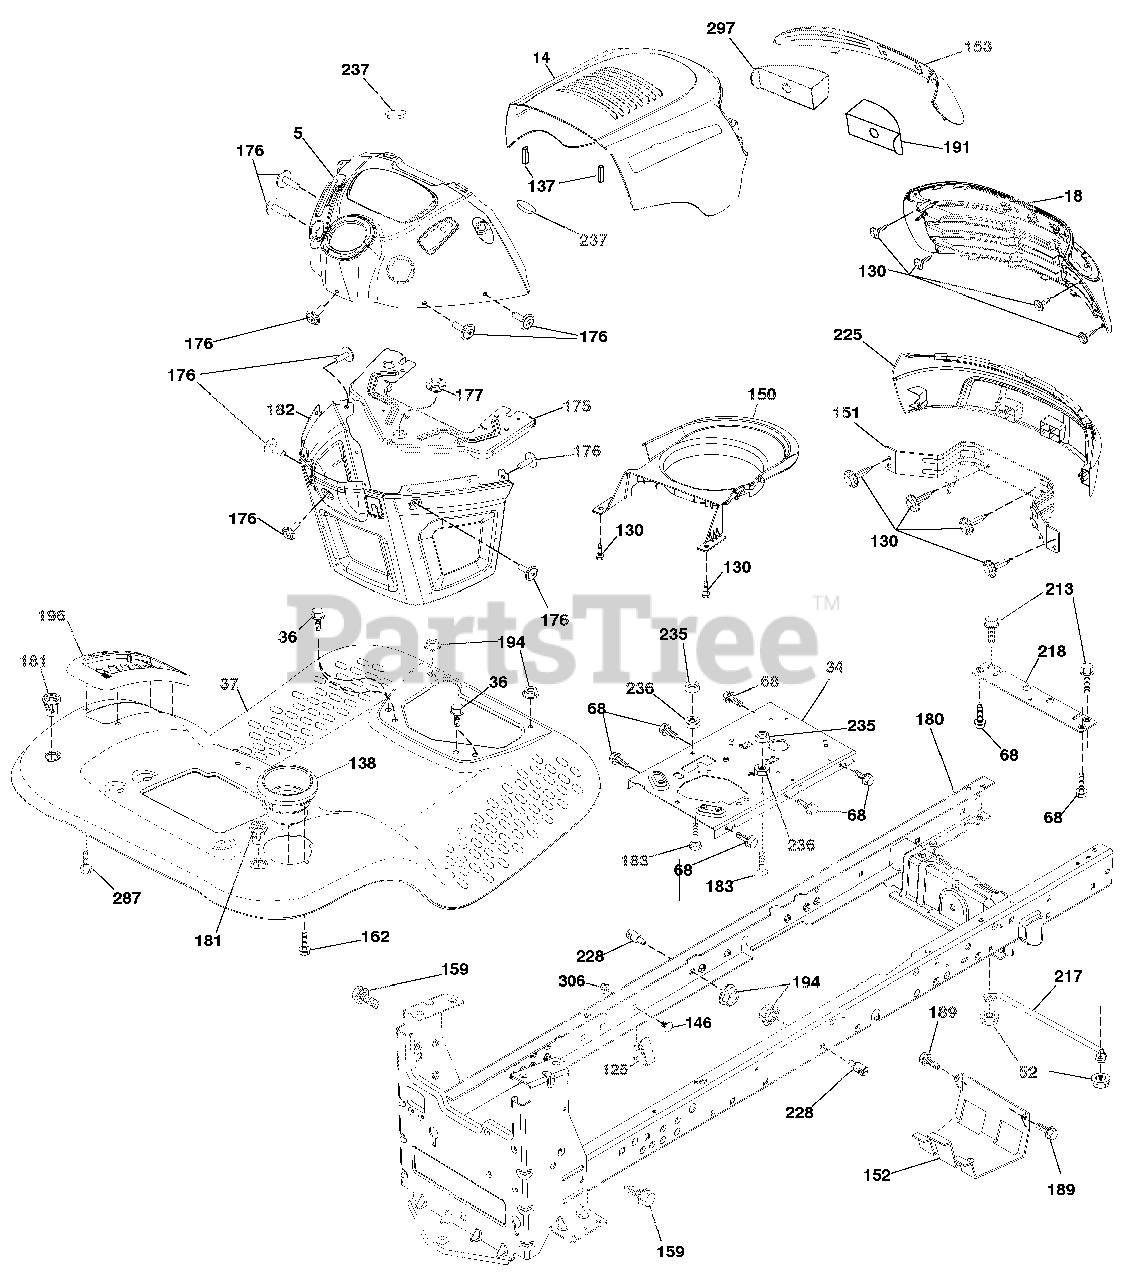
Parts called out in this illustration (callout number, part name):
5	DASH.P/L.TEX.CABLE
18	GRILLE
34	PLATE ENGINE WELDED CHASSIS
36	SCREW.5/16-18X3/4.SMGML.TAP/R
37	FENDER TLT W/CPH W/FW 422
52	Nut, Hex, Crownlock 5/16-18
68	SCREW.THDROL.5/16-18 X 1/2TYTT
125	CLIP.FUEL.LINE
137	BUMPER HOOD
138	CUPHOLDER TL TEX 428
150	AIR DUCT.INTAKE.B&S
151	Bracket Pivot
152	SHIELD.BROWNING.W/TEX
153	LENS, ARIENS
159	SCREW.HEXWSH THDR3/8-16X3/4.BL
162	SCREW.HEX.WSH.HI-LO.1/4X1/2UNC
175	CROSSMEMBER.LT
176	SCREW.#10-24X5/8.RND.QUDRX.GIM
177	BUSHING.STEERING.LT
180	CHASS WLDMT TL 12 GA/2PC 18/22
181	BUSHING MNT FEND CRGO BLK TEX
182	DASH LOWER
183	BOLT.FIN.HEX.5/16-18 UNC X1-1/
189	SCREW.5/16-18X3/4.SMGML.TAP/BL
191	INSERT REFLECTIVE RH
194	Nut, Lock Hex Flange 5/16-18 u
196	CONSOLE ASM.DECKLFT.BL/RBT.TLT
213	BOLT.HEX.HD.1/4-20UNC X 3/4
217	ROD.PIVOT.HOOD
218	X-PIECE.HOOD.STOP.NON/STEALTH
225	BUMPER
228	STUD.FASTNER.W/'D'ANTI-ROTATIO
235	SPACER.FENDER
236	NUT.CENTER LOCK.5/16-18 UNC
237	PLUG.MOUNT.CARGO
287	SCREW.HEX.WASHEAD.1/4-20 X 3/8
297	INSERT REFLECTIVE LH
306	Nut, Hex, Flangelock 3/8-16
